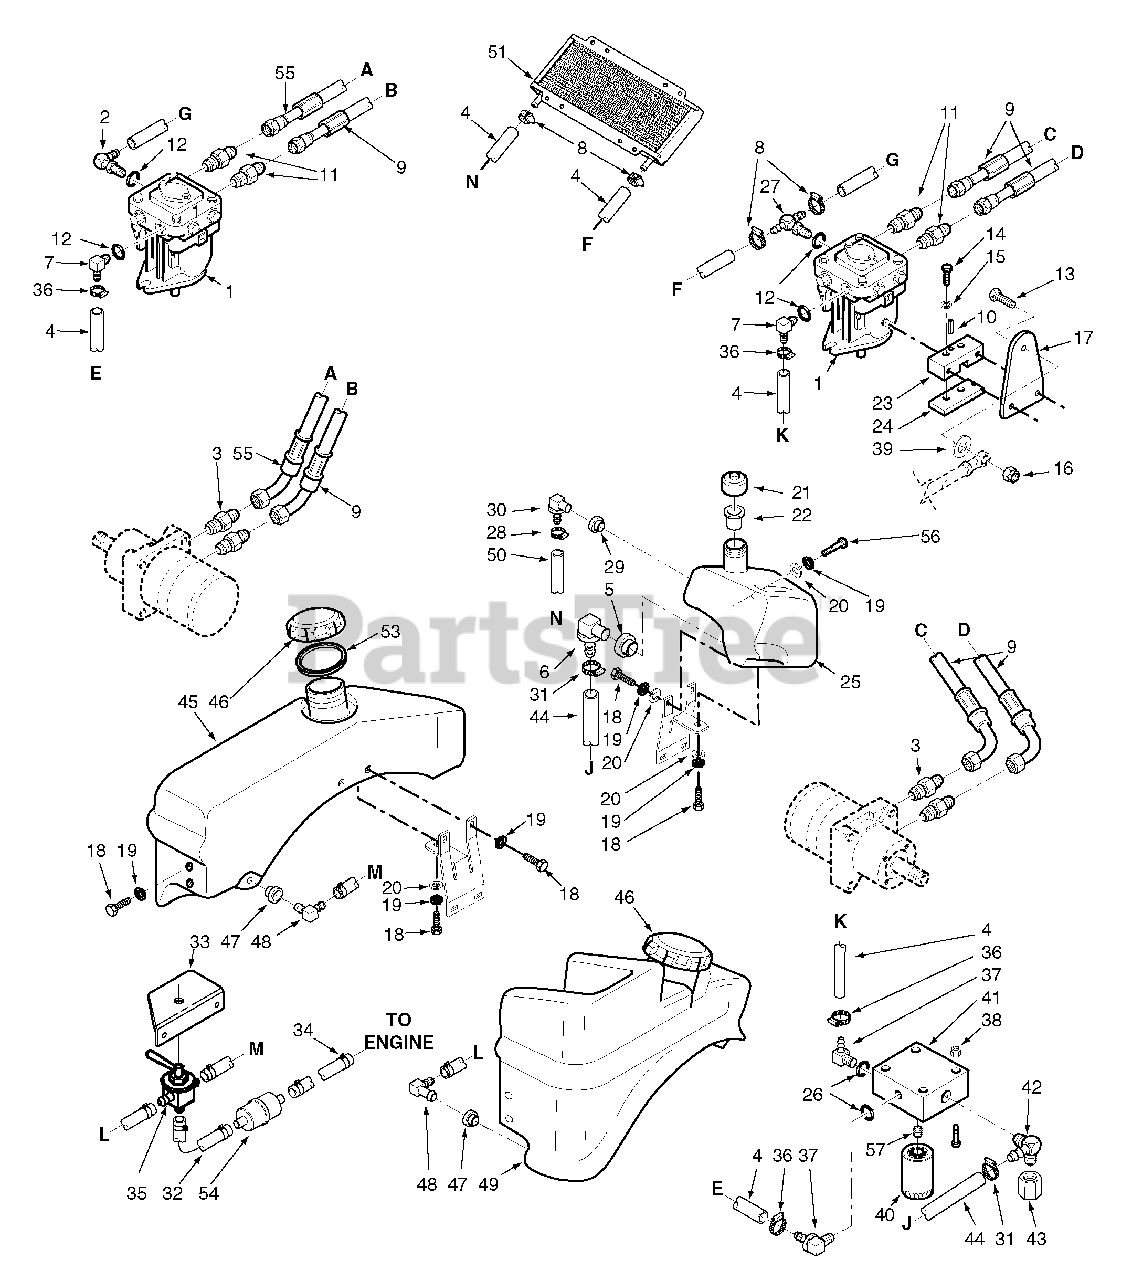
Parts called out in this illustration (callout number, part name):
1	Pump, BDP-10A-316 (L.H.)
1	Pump, BDP-10A-419 (R.H.)
2	Elbow, 90 Degree 9/16 O-Ring x 3/8 Hose
3	Fitting, 1/2" JIC x 5/8 O-Ring
4	Hose, 3/8 Pushlock (Specify length)
5	Bushing
6	Fitting
7	Elbow, 90 Degree 9/16 O-Ring x 3/8 Hose
8	Hose Clamp, .69 Dia.
9	Hose Assembly
10	Roll Pin
11	Fitting, 1/2" JIC x 1/2" O-Ring
12	O-Ring
13	Bolt, Hex Head 3/8-16 x 1-1/2"
14	Bolt, Hex Head 1/4-20 x 1-1/4"
15	Lockwasher
16	Nut, Elastic Stop 3/8-16
17	Control Lever
18	Bolt, Hex Head 5/16-18 x 3/4"
19	Lockwasher, 5/16
20	Flatwasher, 5/16-.375 x .875 x .083
21	Cap, Hydraulic Tank
22	Insert, Filler Neck
23	Control Block
24	Clamp Plate
25	Hydraulic Tank Assembly w/fittings
26	O-Ring
27	Tee Fitting, O-Ring to Barb
28	Clamp, .69 Max. / .25 Min. Dia.
29	Bushing
30	Elbow, 0.38 Hose
32	Fuel Hose, 1/4 ID
33	Bracket Fuel Valve
34	Clamp, Fuel Hose 1/4 Hose ID
35	Valve, Fuel Shutoff
36	Clamp, .69 Max. / .25 Min. Dia.
37	Elbow, 1/4 NTP x 3/8 Hose Barb
38	Nut, Serr. Flange 5/16-18
39	Flatwasher, 3/8-.391 x .938 x .105
40	Oil Filter
41	Filter Head Assembly
42	Fitting, Tee Special
43	Cap, 3/4-16 JIC
44	Hose, Filter Inlet
45	Fuel Tank RH
46	Cap, Fuel Tank
47	Tank Bushing
48	Elbow, 90 Degree
49	Fuel Tank LH
50	Hose, 3/8 Pushlock 15" Long
51	Cooler, Transmission
52	Screw, 1/4-20 x 2"
53	Gasket, Gas Tank Cap
54	Fuel Filter
55	Hose Assembly
56	Bolt, Hec Head 5/16-18 x 1-1/2
57	Nipple, Oil Filter 1.0-12 UNF-2A x 1-1/4"
58	Bolt, Hex Head 5/16-18 x 2"
